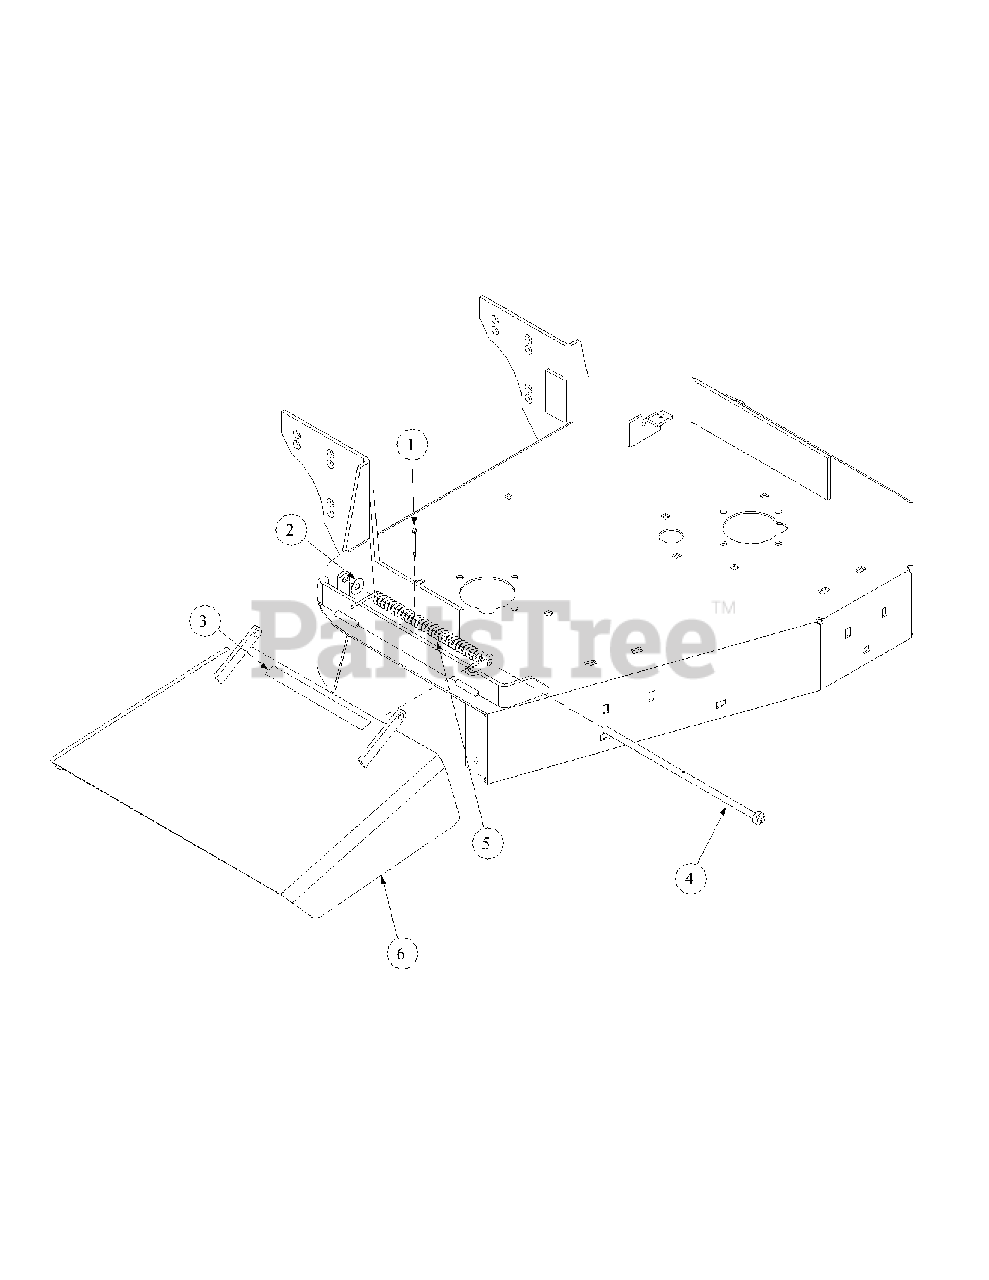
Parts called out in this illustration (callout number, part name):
1	Cotter Pin, 5/32 x 1 1/2 Zinc
2	Flat Washer, 3/8, Zinc
3	Decal, Cut Line
4	Pin, Deflector Assembly, Weldment1
5	Torsion Spring
6	Chute Assembly Discharge
